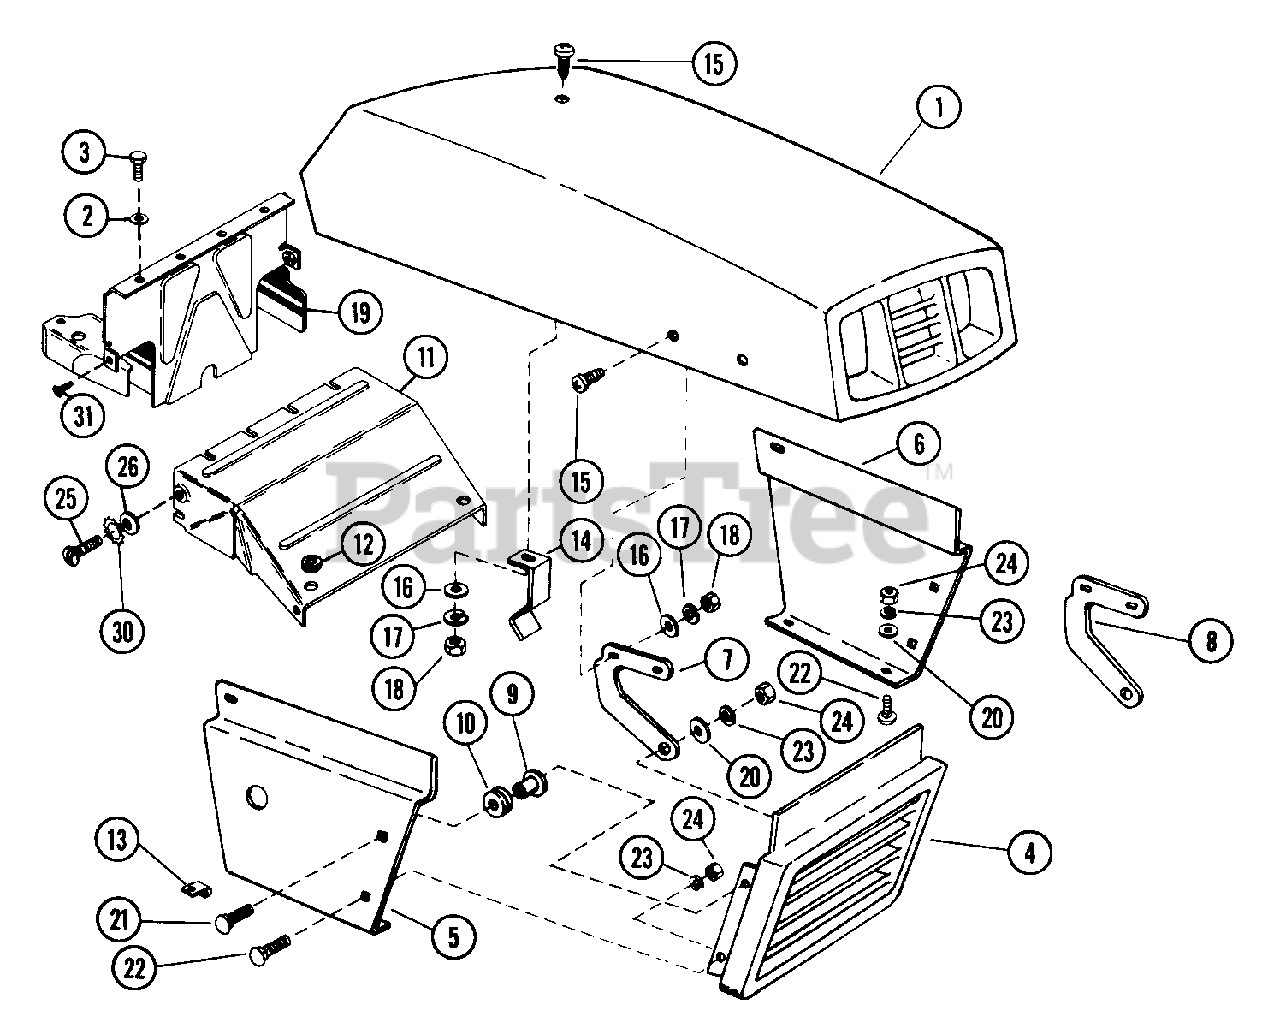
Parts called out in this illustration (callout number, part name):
1	HOOD & GRILL
2	WSHR-FL-STL .268X.562X.046 PL
3	BLT-HEX .25-20X.63 PL GR2
5	SIDE SHEET R. H.
5	SIDE SHEET R.H.
6	SIDE SHEET L.H.
7	R.H. HOOD HINGE
8	L.H. HOOD HINGE
9	SPACER -FLANGED .390X.500X.781
10	GROMMET .50IDX.812OD
11	MUFFLER SHIELD
12	GROMMET .438ID X .688 OD
13	J-CLAMP
14	HOOD STOP
15	SCR-MCH .25-20X.75 SLTR PL
16	WSHR-FL-STL.281X.62X.065 PL
17	WSHR-LK .250X.077 HVY PL
18	NUT-HEX .250-20 PL
19	EXHAUST MANIFOLD SHIELD
20	WSHR-FL-STL .438X1.0X.083 PL
21	BLT-RDHDSQNK .38-16X2.00 SHTYW
22	BLT-RDHDSQSHNK .38-16X1.00 PL
23	WSHR-LK .375X.094 MED PL
24	NUT-HEX .375-16
25	SCR-MCH .31-18X.75 TSKBHD PL
26	WSHR-FL-STL.344X.688X.065PL
30	WSHR-LK-INT .313X.030 PL
31	SCR-CAP CR SEMS .25-20X.50 PL
